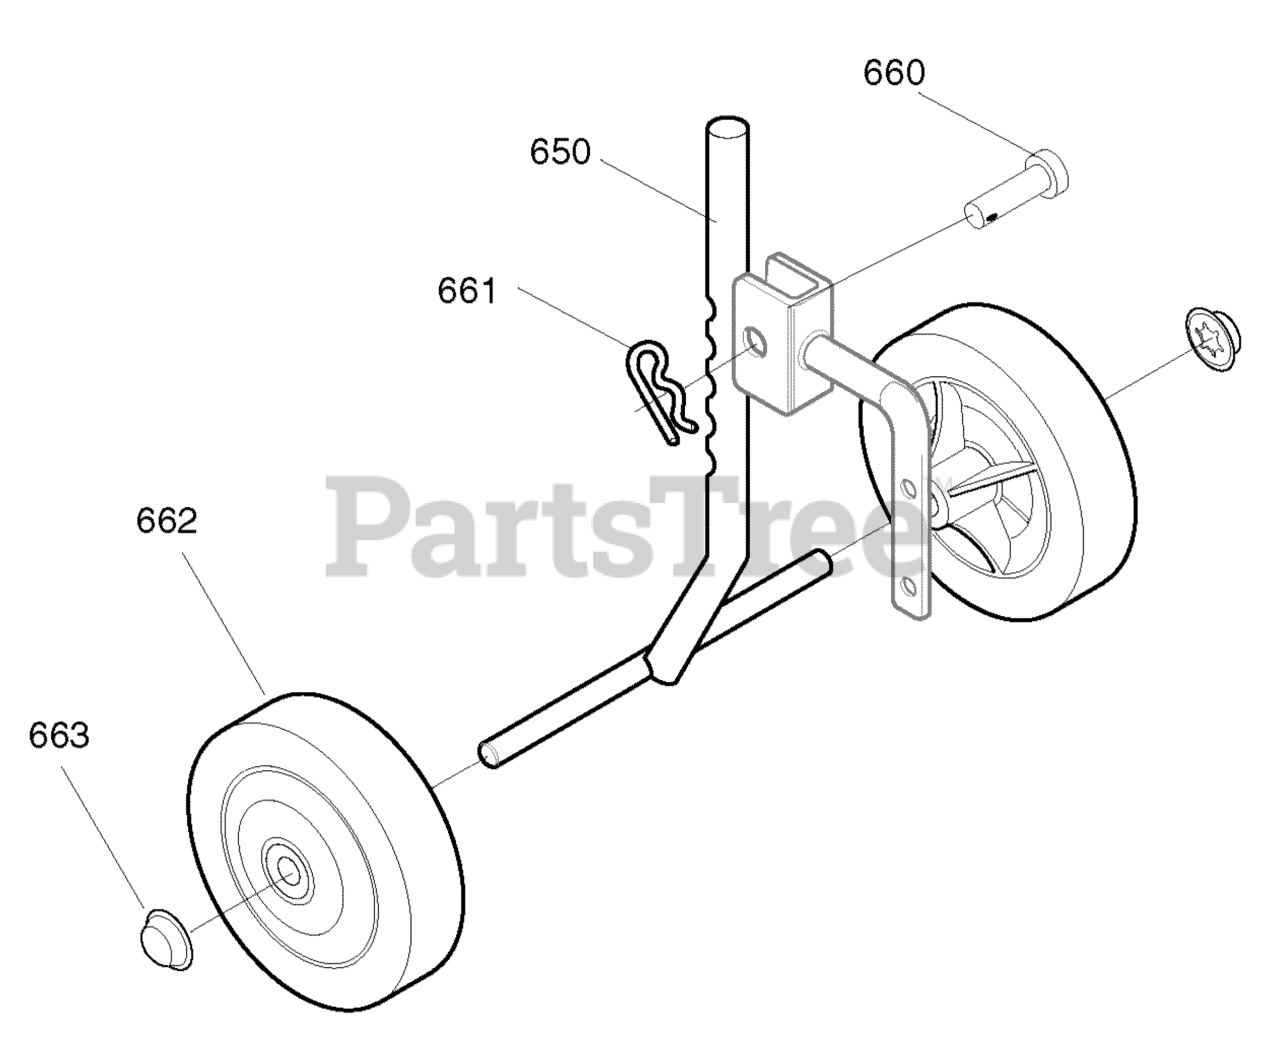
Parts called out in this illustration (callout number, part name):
650	Wheel Support Assy.
660	Clevis Pin
661	Hair Pin
662	Tire & Rim
663	Push On Nut
